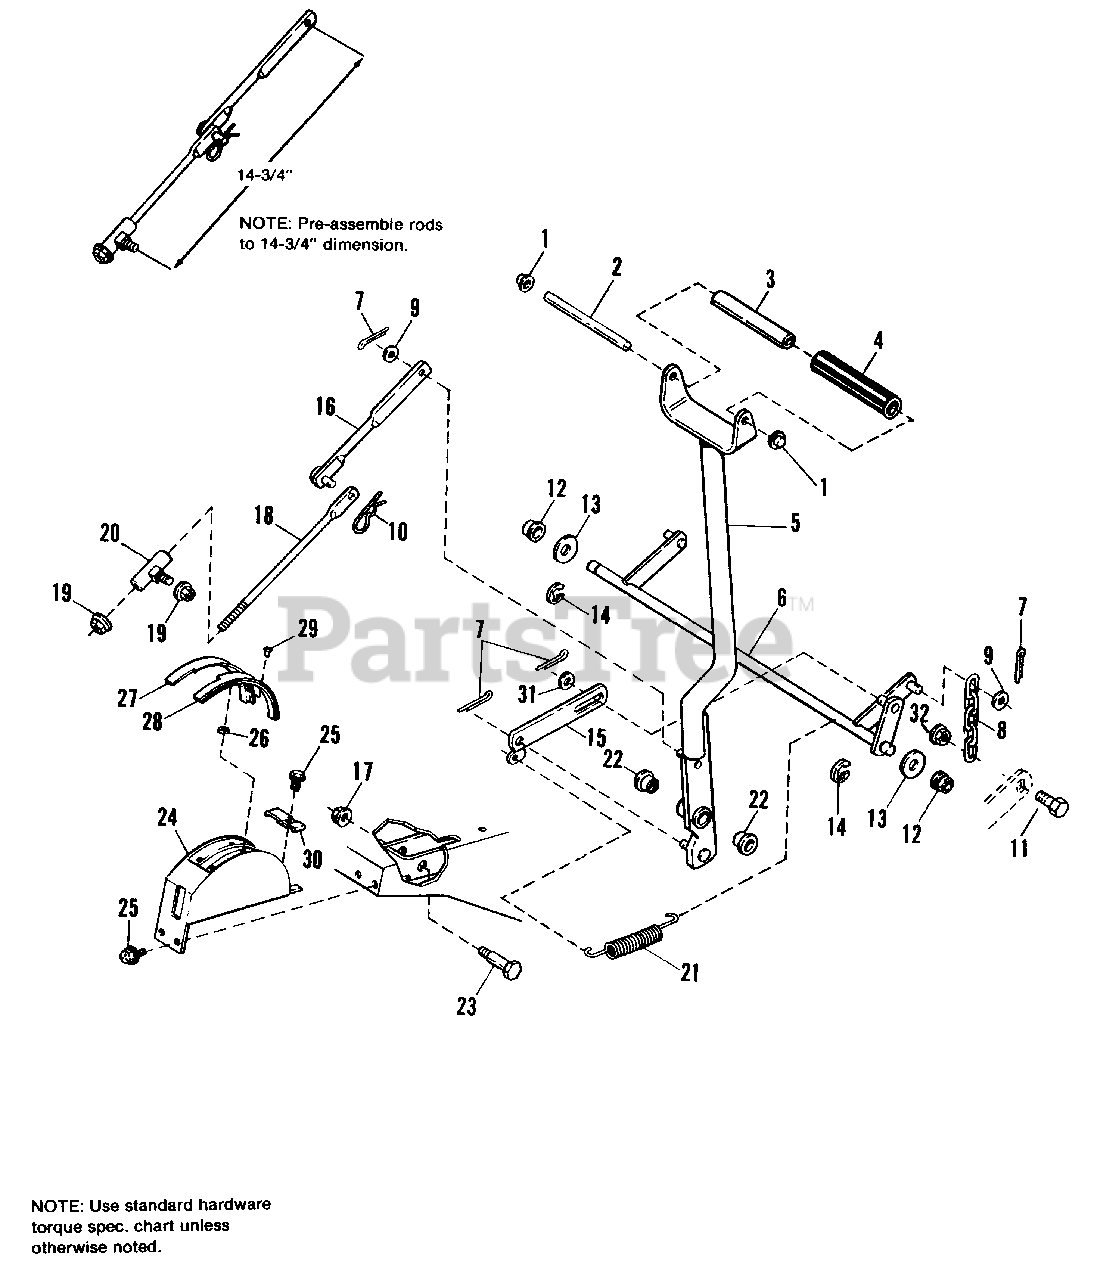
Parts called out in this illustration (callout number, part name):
1	PUSH NUT
2	PIN, Handle
5	HANDLE ASSY., Lift
6	SHAFT ASSY., Lift
7	PIN, Cotter
8	CHAIN, Lift
10	COTTER PIN, Hairpin
11	CAPSCREW, 5/16-16 x 1
12	BUSHING, Nylon
13	WASHER, Plain
14	KLIPRING, 1/2
15	BAR ASSY., Lift
16	LIFT ROD ASSY.
17	NUT, Whizlock, 3/8-16
18	LIFT ROD, Lower
19	NUT, Hex, Esna Lock, 3/8-16
20	YOKE ASSY., Pivot
22	BUSHING, Flanged
23	BOLT, Shoulder
24	COVER, Lift Lever
25	SCREW, Taptite #10-24 x 1/2
27	STRIP, Rubber, R.H.
28	STRIP, Rubber, L.H.
29	RIVET, Push
30	CLAMP, Cover
31	WASHER, Plain, 3/8
32	NUT, Hex, Flange Lock, 5/16-18
